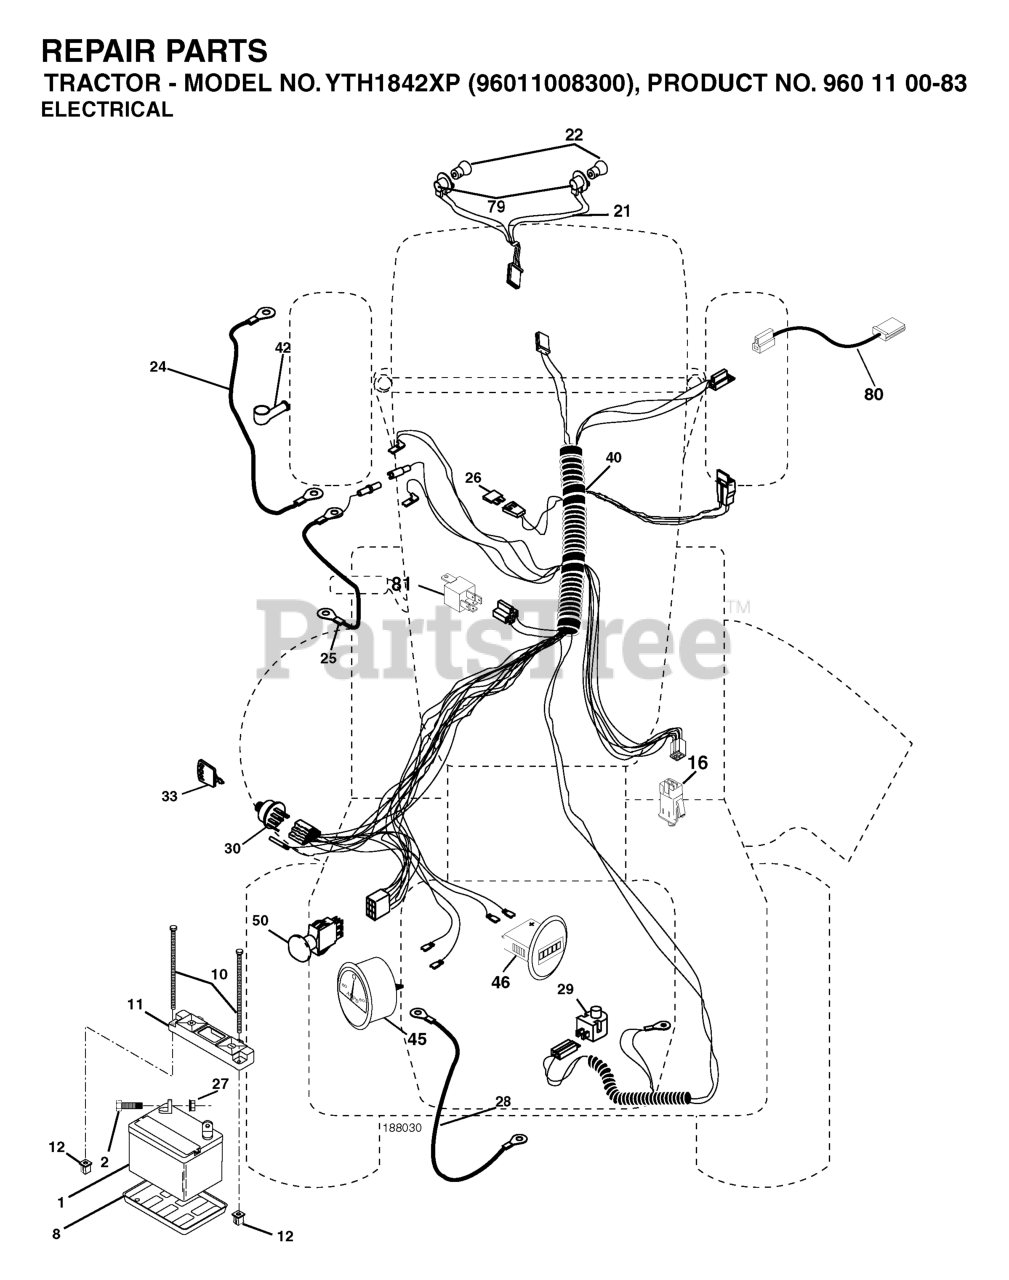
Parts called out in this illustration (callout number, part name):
1	BATTERY 12V .35 AMP
2	BOLT.HEX.1/4.X.3/4.DICHROMATE
8	BATTERY TRAY T
10	BOLT 1/4-20 X 7.5
11	BATTERY HOLDDOWN FRONT MOUNT
12	NUT, PUSH NYLON 1/4" BATTERY
16	SWITCH INTERLOOK PUSH-IN
21	HARNESS.W/LIGHT SOCKET
24	CABLE BATTERY 6 GA 22" W/16W
26	FUSE 20AMP
27	NUT
28	CABLE GROUND 6 GA 21" 90T BLK
29	SWITCH.SEAT.DP W/RAMPS
30	IGNITION SWITCH
33	KEY MLD GEN DELTA
41	SCREW
42	TERMINAL COVER
43	SOLENOID
45	RP AMMETER.ROUND.SILVER.DELTA
46	RP HOURMETER SNAP-IN
50	RP.PTO.SWITCH.8 TERMINAL.BLACK
79	BULB HOLDER ASM.
80	HARNESS, CLUTCH
81	RELAY.ASSY.T
